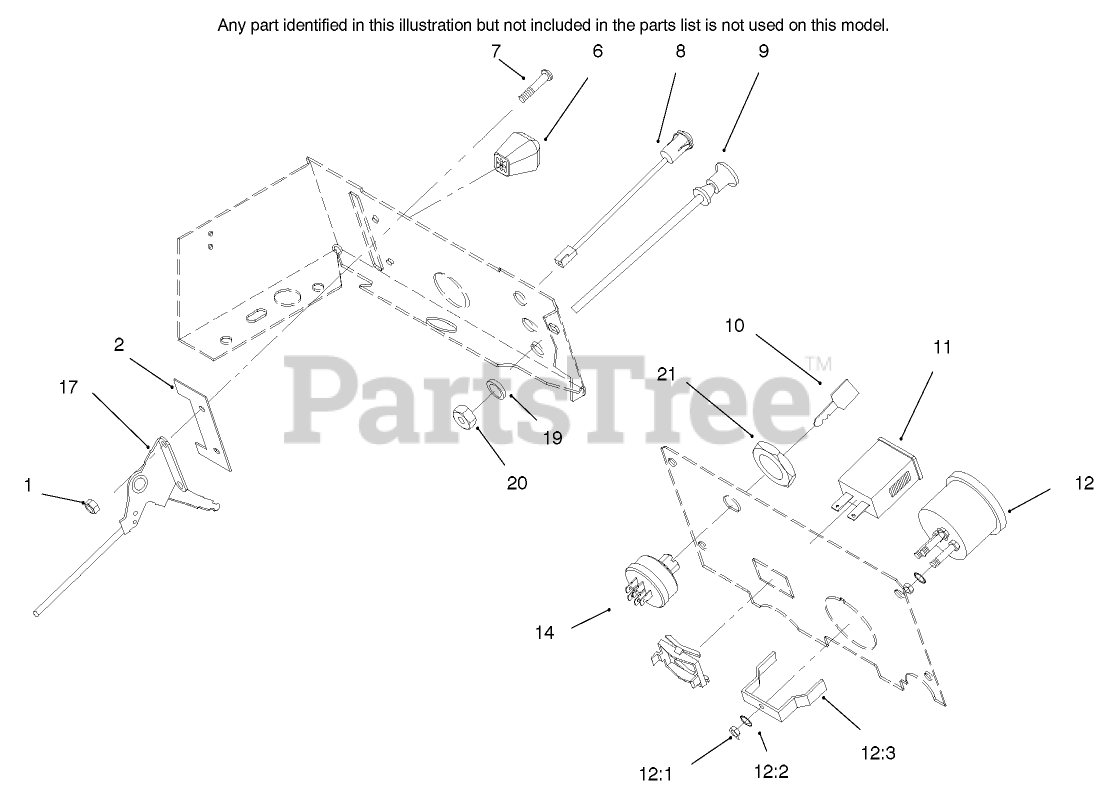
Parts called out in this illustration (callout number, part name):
7	SCREW-PPH
8	LIGHT-INDICATOR
9	CHOKE CONTROL ASM
10	KEY-IGNITION
11	HOURMETER
12	VOLTMETER
12:1	NUT-HEX
12:3	CLAMP-MOUNTING
14	SWITCH-IGNITION
17	THROTTLE CONTROL ASM
19	WASHER-FLAT
20	NUT-HEX PALNUT
